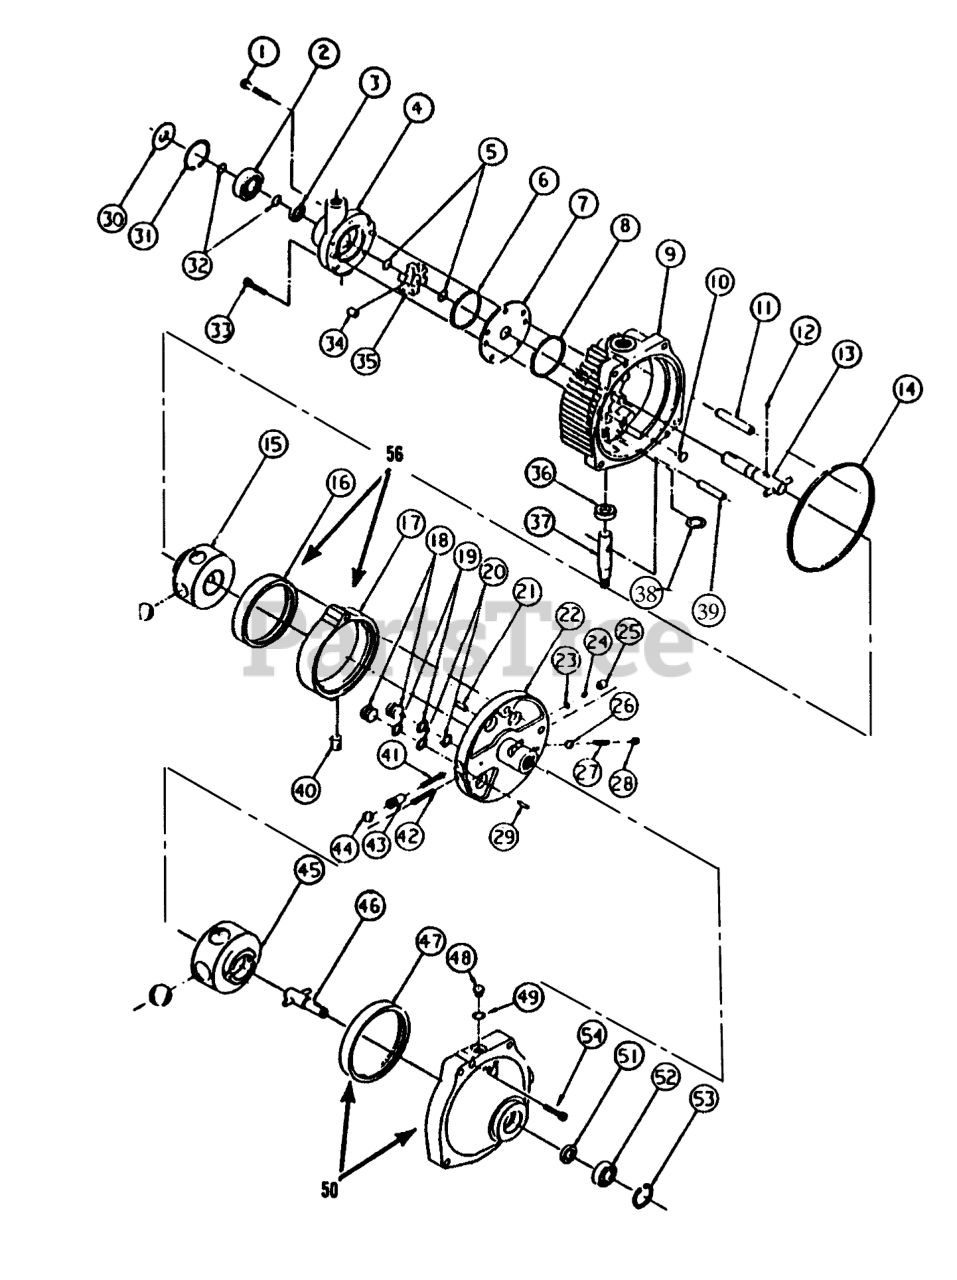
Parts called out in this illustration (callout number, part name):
1	Screw
2	Bearing-Input
3	Seal
4	Housing-Pump Assembly (Incl. Ref. #2)
5	Ring
6	Ring-Seal
7	Plate
8	Ring-Seal
9	Cover Assembly (Incl. Ref. #3, 6, 8, 10, 11, 19, 20, 36-39, & 51)
10	Button
11	Pin-Pivot
12	Pin
13	Shaft-Input
14	Ring-Seal
15	Rotor-Pump
16	PUMP-RACE
17	Ring-Cam
18	Piston
19	Ring-Back Up
20	"O"Ring
21	Pin-Coil
22	Pintle Assembly (Inc. Ref. #21, 23-29, &41-44)
23	Ring-Retaining
24	Ball
25	Body-Check Valve
26	Ball
27	Spring-Relief Valve
28	Plug-Relief Valve
29	Pin
30	SHIELD-GRASS
31	RETAINING-RING
32	Ring
33	Screw
34	Roller
35	Carrier
36	Seal
37	Kit-Control
38	Washer
39	Dowel
40	Insert-Cam Ring
41	Spring-Acc. Valve
42	Spring-Acc. Valve
43	Body-Acc. Valve
44	Ball
45	Rotor-Motor
46	Shaft-Output
47	Race-Motor
48	Plug-"O"Ring (incl. Ref. #49)
49	O-Ring
50	Body Assembly (Incl. Ref. #51, 53 & 54)
51	Seal ASM
52	Bearing-Output
53	Retaining Ring
54	Screw
55	Kit-Seal, Overhaul (Incl. Ref. #3, 6, 8, 14, 19, 20, 36, 49 & 51)
56	Ring-Cam
